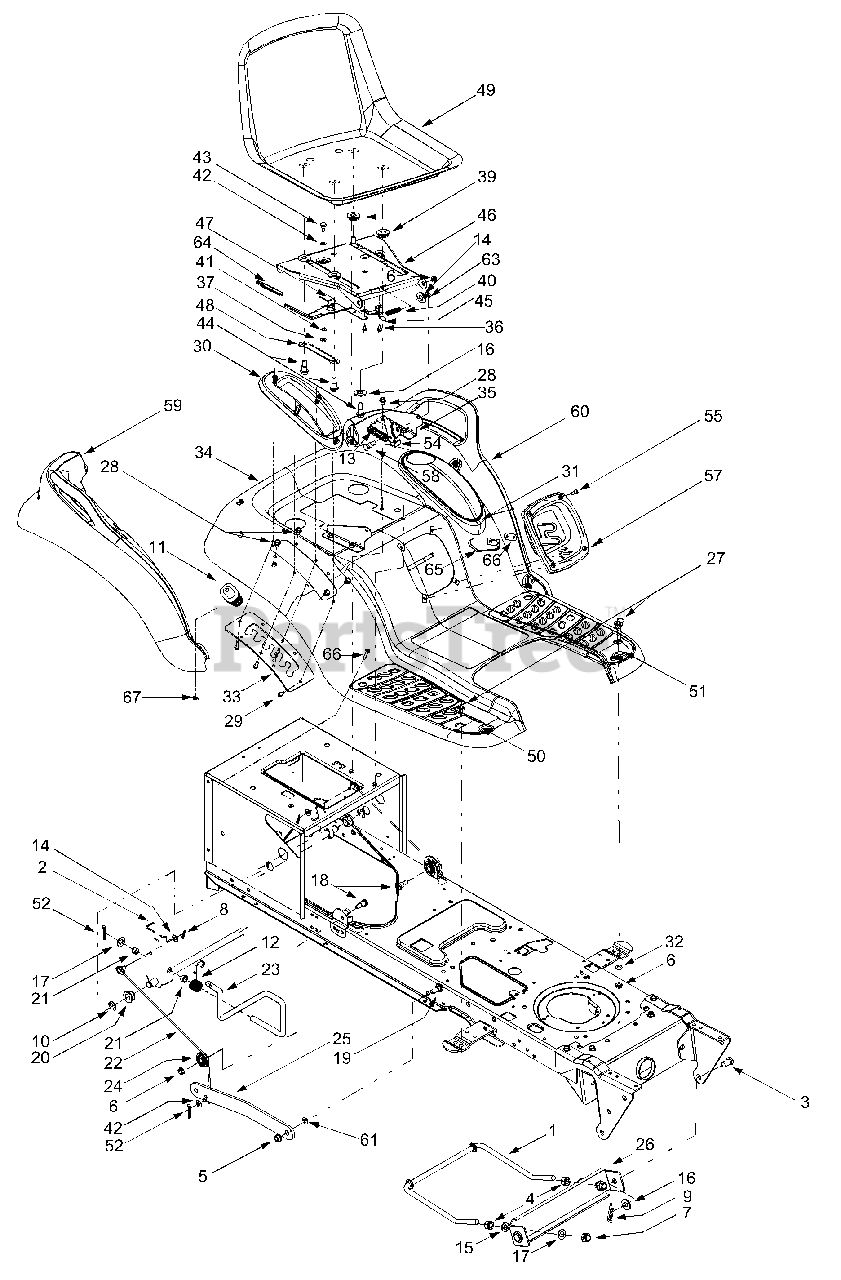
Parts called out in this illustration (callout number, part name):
1	Deck Stabilizer Rod
3	Clevis Pin,.5 x.78
4	Hex Nut, 1/2-13
5	Flange Lock Nut, 3/8-16
6	Flange Lock Nut, 5/16-18
7	Hex Nut, 1/2-13
8	Internal Cotter Pin
9	Internal Cotter Pin
10	E-ring
11	Handle Grip
12	Torsion Spring
13	Extension Spring,.84 x 4.6
14	Flat Washer, 5/16
15	Lock Washer, 1/2
16	Flat Washer,.31 x 1.062 x.134
17	Flat Washer,.51 x 1.12 x.06
18	Hex Cap Screw, 5/16-18 x.62
19	Shoulder Screw, 3/8-16
20	Hex Flange Bearing
21	Snap Flange Bearing
22	Lift Cable, 16.16
23	Lift Handle
24	Roller Pulley
27	Carriage Bolt, 5/16 x.62
28	AB Screw, 5/16-12 x.75
29	Self-tapping Screw, 1/4-15 x.75
30	Lift Lever Cover
31	Cover w/ Cup Holder
32	Flat Washer,.349 x 1.0 x.063
36	Screw, #10-16 x.375
37	Hex Flange Lock Nut, 1/4-20
39	Spacer
40	Compression Spring,.41 x 1.5
41	Spring Washer,.265 x.562 x.025
42	Flat Washer,.344 x.62 x.03
43	Shoulder Screw,.340 x.285,1/4-20
44	Shoulder Screw,.50 x.825, 3/8-16
45	Seat Stop
48	Seat Adjustment Selector
49	High Back Seat, Yellow
50	RH Foot Pad
51	LH Foot Pad
52	Cotter Pin
54	LH Seat Lift Bracket
55	Self-tapping Screw, 1/4-20 x 1.00
57	Shift Lever Cover
58	Shoulder Screw,.437 x.286
59	RH Fender Flare
60	LH Fender Flare
61	Flat Washer,.53 x.93 x.050
63	Side Seat Adjuster Grip
64	Switch
65	Insulator Nut Plate
66	Screw, 1/4-20 x 1.00
67	Hex Nut, 1/4-20
